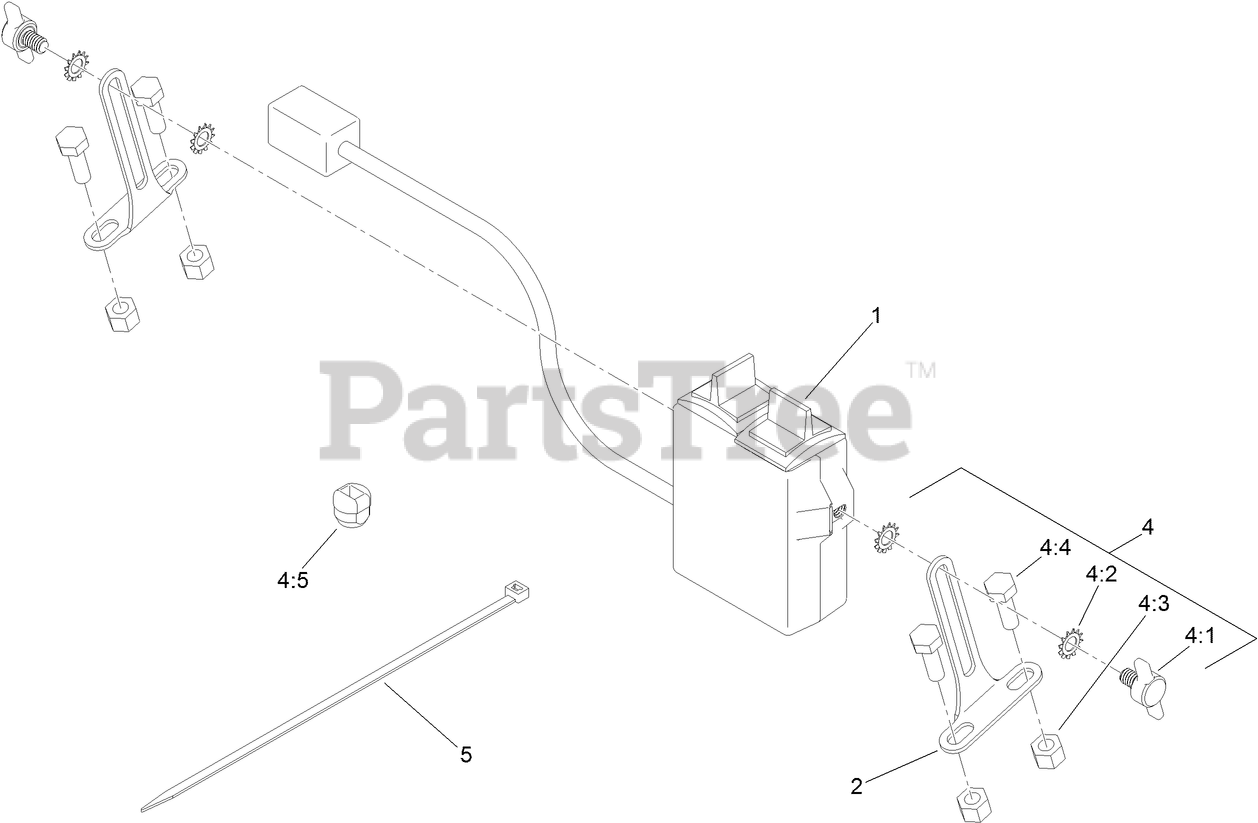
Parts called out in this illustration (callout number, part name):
1	CONTROL,SWITCH BOX,GRANDSTAND
2	BRACKET,LG,ATV/UTV CB
4	KIT-HDW,ELECT,GRANDSTAND
4:1	THUMB SCREW,1/4-20 X 7/16,ATV CB
4:2	STAR WASHER 1/4,ATV CB
4:3	NUT,1/4-20,NYL INS,YZN
4:4	HHCS,1/4-20X3/4,GR5,YZN
4:5	STRAIN RELIEF,.625 DIA X .125 PANEL T
5	CABLE TIES, (15) COUNT, 50#, 15-1/2,
